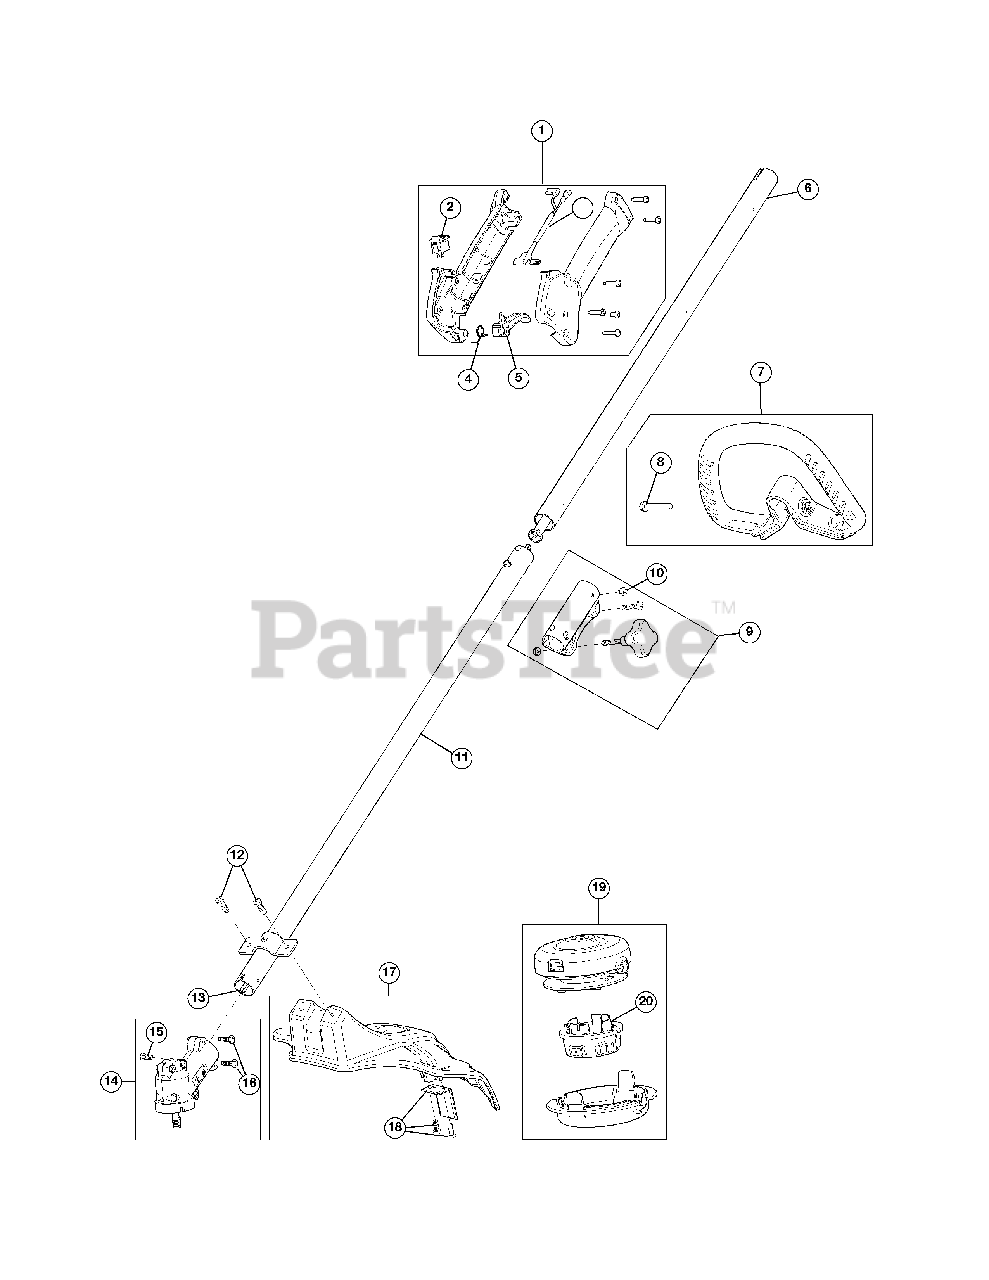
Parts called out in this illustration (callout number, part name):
1	Throttle Housing Assembly(includes2-4)
3	Throttle Cable Assembly
4	Throttle TriggerSpring
5	Throttle Trigger
6	Upper Drive Shaf tHousin gAssembly
7	D-Handle Assembly(includes8)
9	Split Boom Coupler(includes10)
9	Knob, Adjustment
9	Nut, Retaining
10	Coupler Anti-Rotation Screw
11	Lower Drive Shaft Housing Assembly
12	Shield Mounting Screws
13	Lower Flexible DriveShaft
14	GearBox Assembly( includes15and16)
15	Anti-Rotation Screw
16	Gearbox Mounting Hardware
17	Shield Assembly(includes18)
18	BladeAssembly
19	Cutting Head Assembly(includes20)
20	Bump Knob
